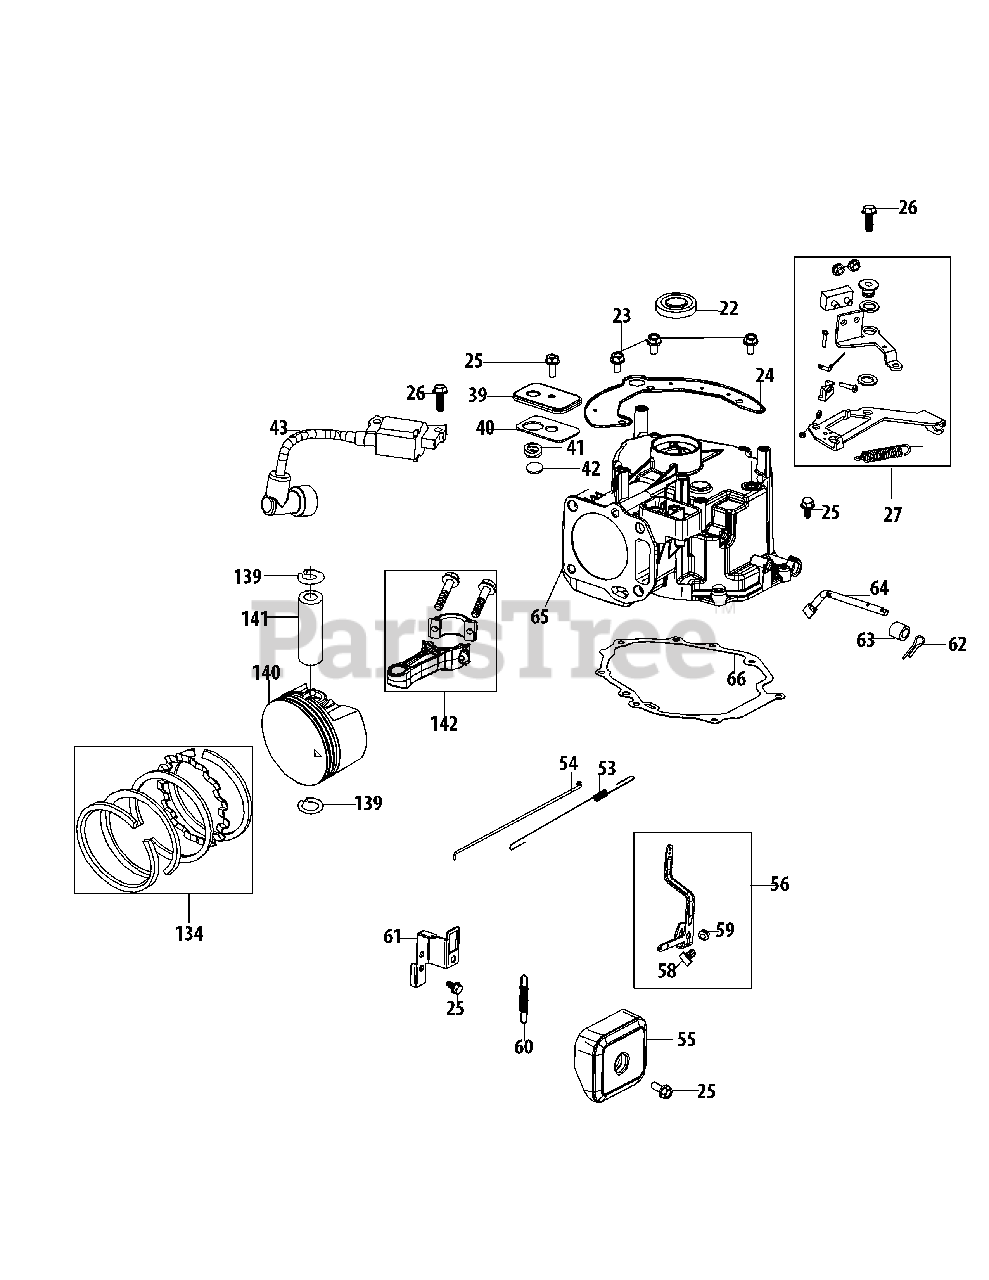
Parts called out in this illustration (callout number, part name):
22	Upper Crankshaft Seal
23	Bolt M6×10 Shroud Cover Plate
24	Shroud Cover Plate
25	Bolt M6X14 Multi-Purpose
26	Bolt M6×25 Ignition Coil/Brake
27	Brake Assembly
39	Breather Cover Plate
40	Breather Gasket
41	Breather Valve Spring
42	Breather Valve
43	Ignition Coil Assembly
53	Throttle Linkage Spring
54	Throttle Linkage
55	Governor Shield
56	Governor Arm Assembly
58	Governor Arm Bolt
59	Governor Arm Nut M6
60	Governor Spring
61	Component Bracket
62	Governor Arm Shaft Cotter Pin
63	Governor Seal
64	Governor Arm Shaft
65	Crankcase
66	Crankcase Cover Gasket
134	Piston Ring Set
139	Piston Pin Snap Ring
140	Piston
141	Piston Pin
142	Connecting Rod Assembly
